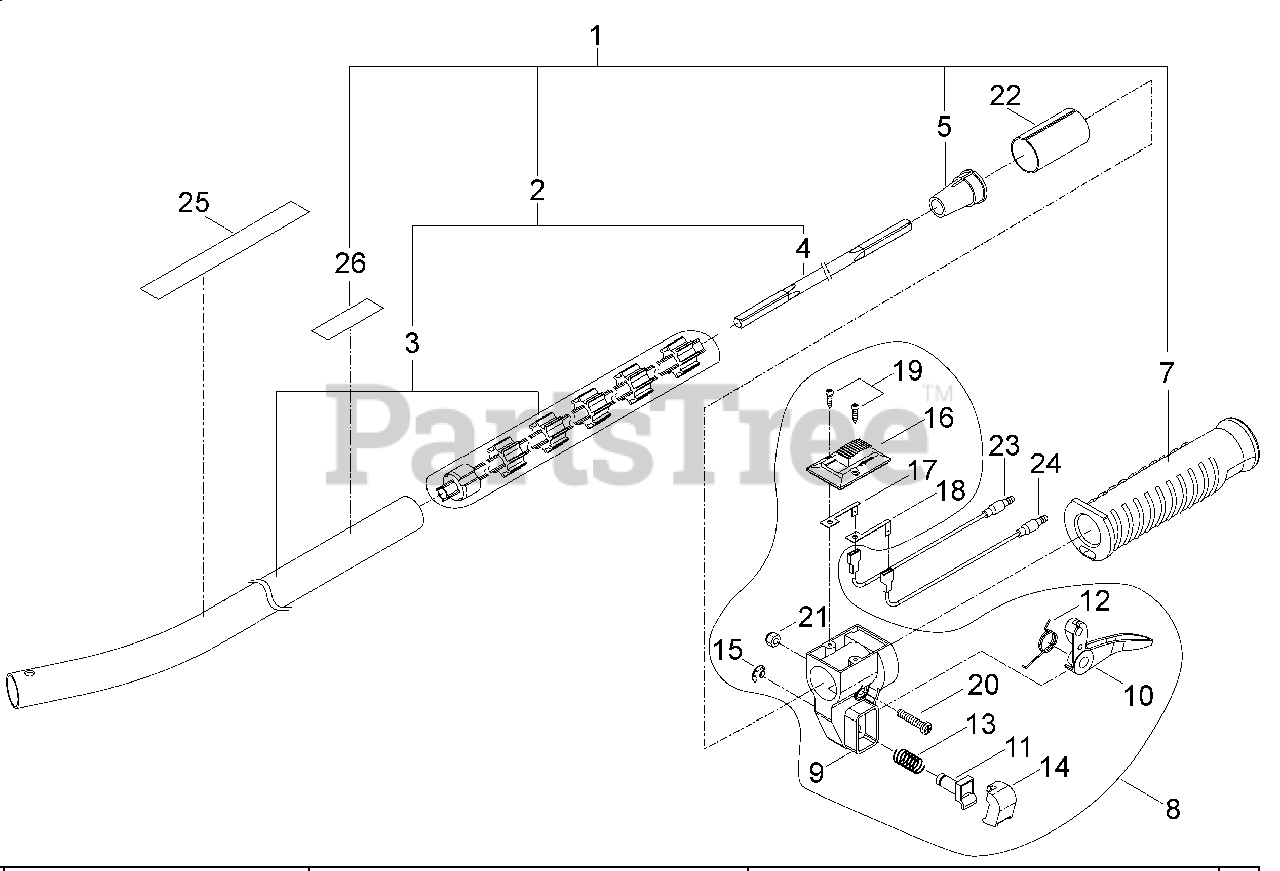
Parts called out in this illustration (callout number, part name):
1	MAIN PIPE ASSY
2	MAIN PIPE & SHAFT ASSY
3	PIPE, MAIN
4	DRIVESHAFT - FLEXIBLE
5	GUIDE, SHAFT
7	GRIP, REAR
8	THROTTLE CONTROL ASSY
9	BODY, THROTTLE
10	TRIGGER, THROTTLE
11	LOCKOUT, THROTTLE
12	SPRING, RETURN
13	SPRING
14	BUTTON, THROTTLE LOCK
15	RING, SNAP
16	SWITCH, ON-OFF
17	PLATE, RIGHT GROUND
18	PLATE, LEFT GROUND
19	SCREW, TAPPING
20	SCREW
21	NUT, NYLON
22	SPACER
23	WIRE, RIGHT LEAD
24	WIRE, LEFT LEAD
25	LABEL, SHINDAIWA PROFESSIONAL
26	LABEL, CAUTION (BLADE CAPABLE)
